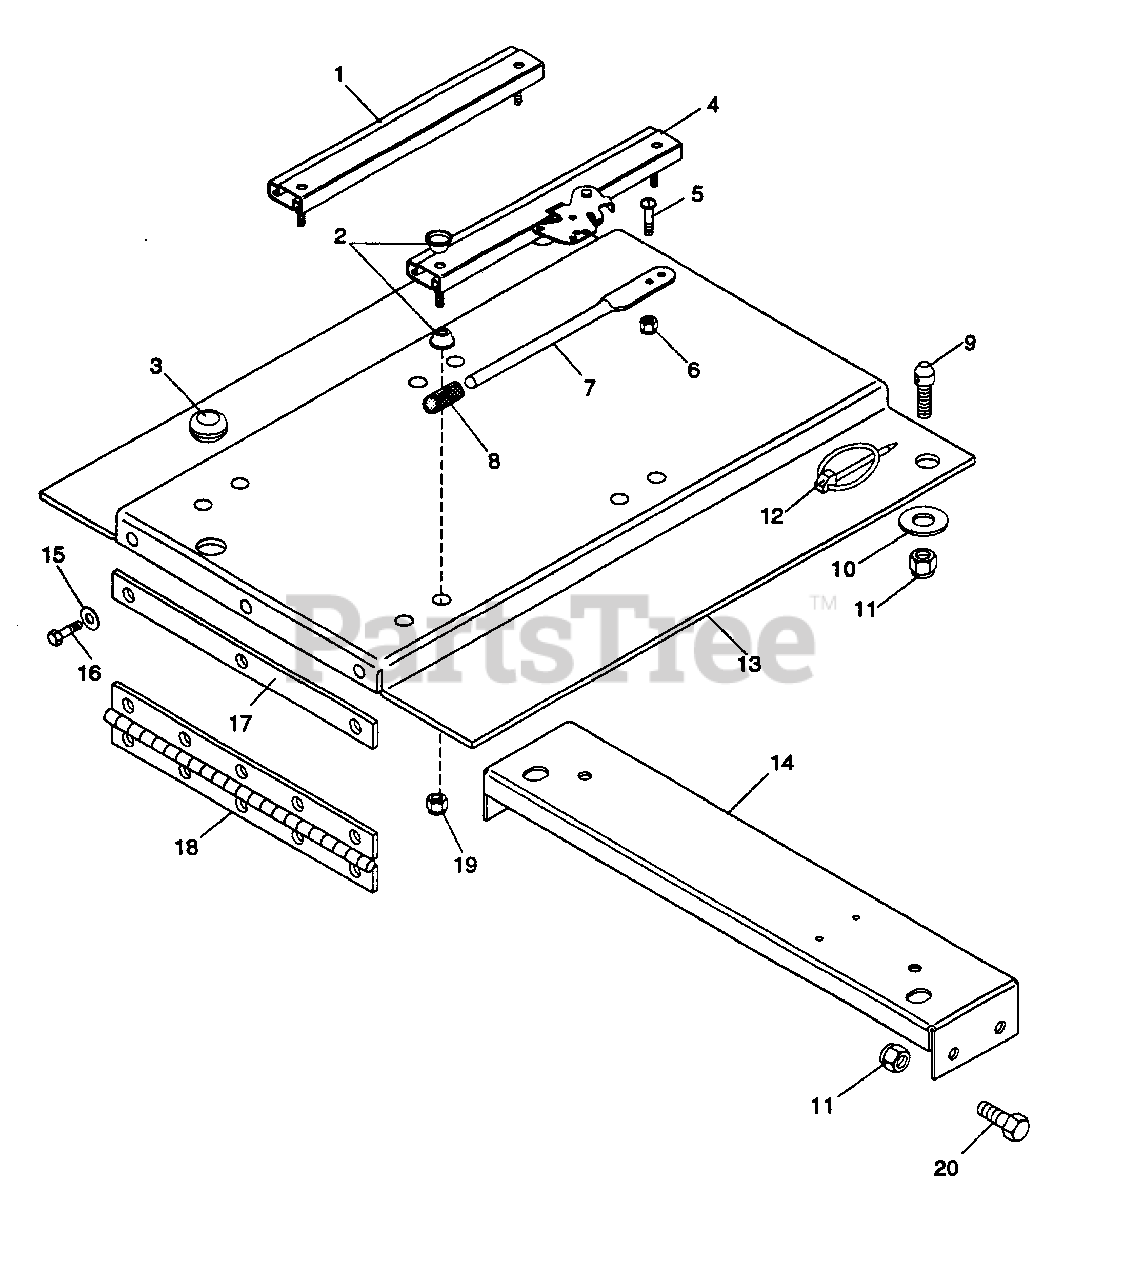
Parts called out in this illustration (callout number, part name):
1	ADJUSTER, SEAT
2	SEAT SLIDE SPACER
3	GRMT .75 X 1.06 X 1.38
4	ADJUSTER, SEAT W/LATCH
5	SCR-MCH 10-24 X .625 P/HD
6	NUT-LK 10-24 NY PL
7	SEAT SLIDE HANDLE
8	TIP - BRAKE LOCK LEVER
9	PIN, CATCH
10	WSHR-FL-STL .531 X 1.062 X .095
11	NUT-LK-NYL .50-13 PL
12	PIN-KLIK .25 X 1.75
13	PLT, DECK
14	BRKT, DECK PLATE
15	WSHR-FL-STL .344 X .688 X .065
16	BLT-HEX .31-18 X .75 PL GR 5
17	PLT, CLAMPING
19	NUT-LK-NYL .312-18 PL
20	BLT-HEX .50-13 X 1 PL GR 5
NS	DECAL, DANGER HAND
NS	DECAL, START
